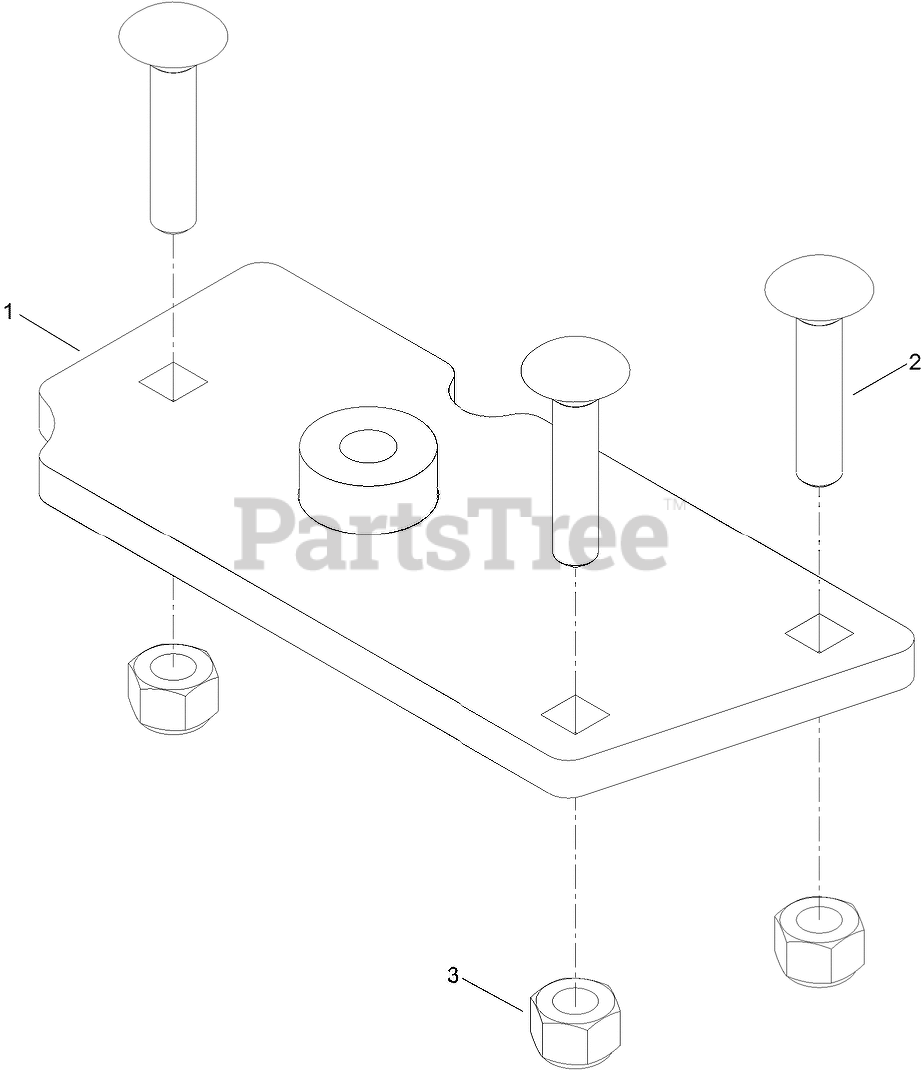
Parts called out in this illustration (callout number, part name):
1	PLATE-FRAME
2	SCREW-CARR
3	NUT-LOCK, NI
